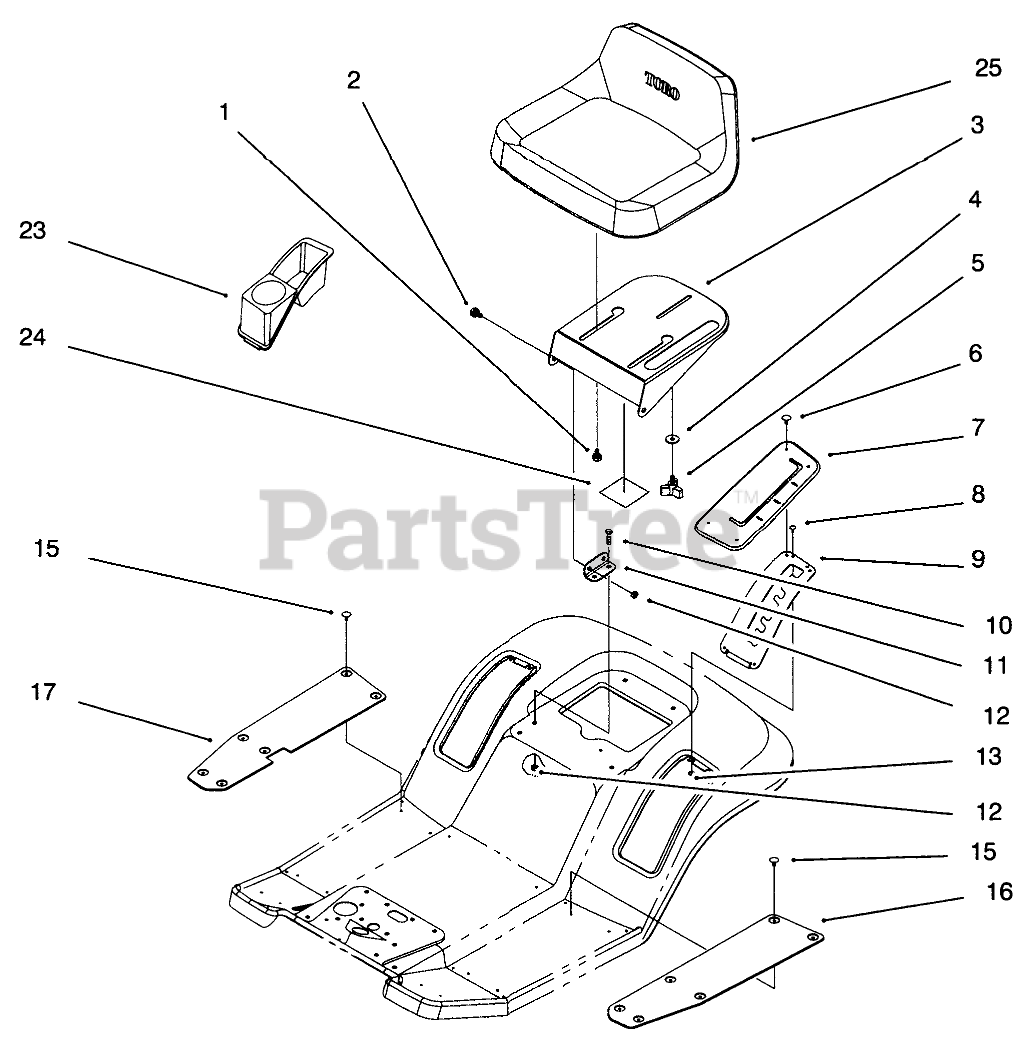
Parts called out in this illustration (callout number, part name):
1	BOLT-SHOULDER
2	BOLT-SHOULDER
3	SEAT SUPPORT (BLACK)
4	WASHER-PIVOT
6	FASTENER-PANEL
7	Cover-HOC (Only On: 71193)
7	Cover-HOC (Only On: 71217)
8	RIVET-BLIND
9	GATE-HOC
10	SCREW-HH
11	BRACKET-PIVOT, SEAT
12	NUT-LOCK, NI
13	WASHER-PLAIN
15	FASTENER-PANEL
16	MAT-FOOT, LH
17	MAT-FOOT, RH
23	TRAY-FENDER
24	Decal-Noise (Only On: 71217)
25	SEAT
